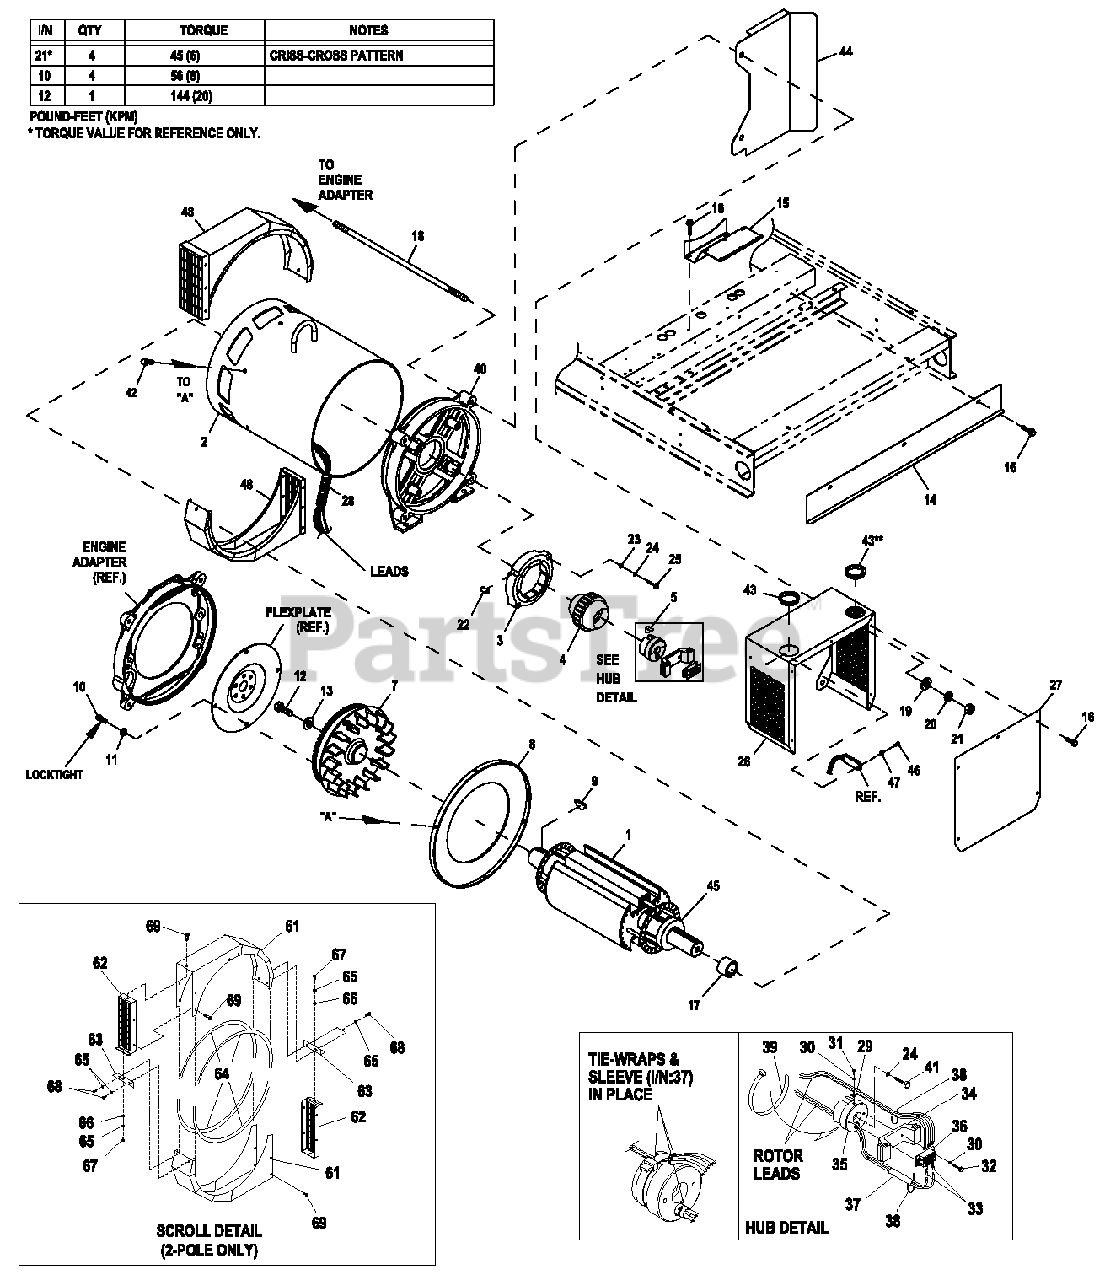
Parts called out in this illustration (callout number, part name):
1	ASSY ROTOR 2390 80KB3 CPL
2	ASSY STATOR 80KW 1PH 2P BRSHLS
3	EXITER FIEL D 2" LG SP D CONN
4	ASSY EXCITER 2.0" STACK 2P
5	KEY SQ 3/8 X 3-1/4 STEEL
7	ASSY FLYWHEEL CPL
8	RING PRESSURE 390 STATOR CAN
9	KEY WOO DRUFF #E
10	SCREW HHC M10-1.5 X 25 C10.9
11	WASHER LOCK M10
12	SCREW HHC M 16-2.0 X 45 G8.8
13	SPACER .69 X 2.75 X .37 ST/ZNC
14	SHROU D LOWER ALTERNATOR EXCITR
15	SHIELD CENTER ALT EXCITER
16	SCREW THF M6-1 X 16 N WA Z/JS
17	COLLAR SLIP FIT 390 MM
18	STU D M14-2.0 X 760 G5 ZINC
19	WASHER FLAT M14
20	WASHER LOCK M14
21	NUT HEX M 14-2.0 G8 YEL CHR
22	PIN DOWEL 1/2 X 1-1/4
23	WASHER FLAT M12
24	WASHER LOCK M12
25	SCREW HHC M12-1.75 X 80 G10.9
26	SHIEL D ALT EXCITER 5.4/6.8 (1 PHASE)
27	COVER EXCITER SHIEL D
28	CON DUIT FLEX 1.25" ID
29	CLAMP VINYL .312 X .203 Z
30	WASHER SHAKEPROOF INT #8
31	SCREW HHM #8-32 X 3/8
32	SCREW HHM #8-32 X 7/8
33	LUG RT-ANG #10/10-12
34	BRIDGE SUPPORT DIODE 15"
35	CAP END ROTOR 390MM
36	ASSY BRIDGE RECTIFIER
37	SLEEVING UL #0 .330 ID (3" LG)
38	TIE WRAP UL 3.9" X .10" BLK
39	TIE WRAP UL 17.7 X .35 BLK HT
40	REAR BEARING CARRIER
41	SCREW HHC M12-1.75 X 60 G10.9
42	SCREW 1/4-20 X 5/8" TAPTITE SS
43	BUSHING SNAP SB-2.5-31
44	SHROUD UPPER ALTERNATOR EXCITR
45	BEARING BALL 6212 SEALED
46	SCREW PHTT #6-32 X 1/2 ZYC
47	WASHER LOCK #6
48	ASSY SCROLL 390 X 60MM CPL
61	SHROUD ALT SHEET METAL CPL 2P
62	SCREEN, 390 SAE ALT 60MM WIDE
63	BRACKET SAE SCROLL TENSIONER
64	VINYL TRIM 1/8" GAP
65	WASHER, SPLIT 1/4"-M6
66	WASHER FLAT 1/4 ZINC
67	SCREW HHC M6-1.0 x 25 LONG
68	SCREW HHC M6-1.0X 1 6 G8.8
69	SCREW SWAGE 1/4-20 X 1/2 Z/YC
